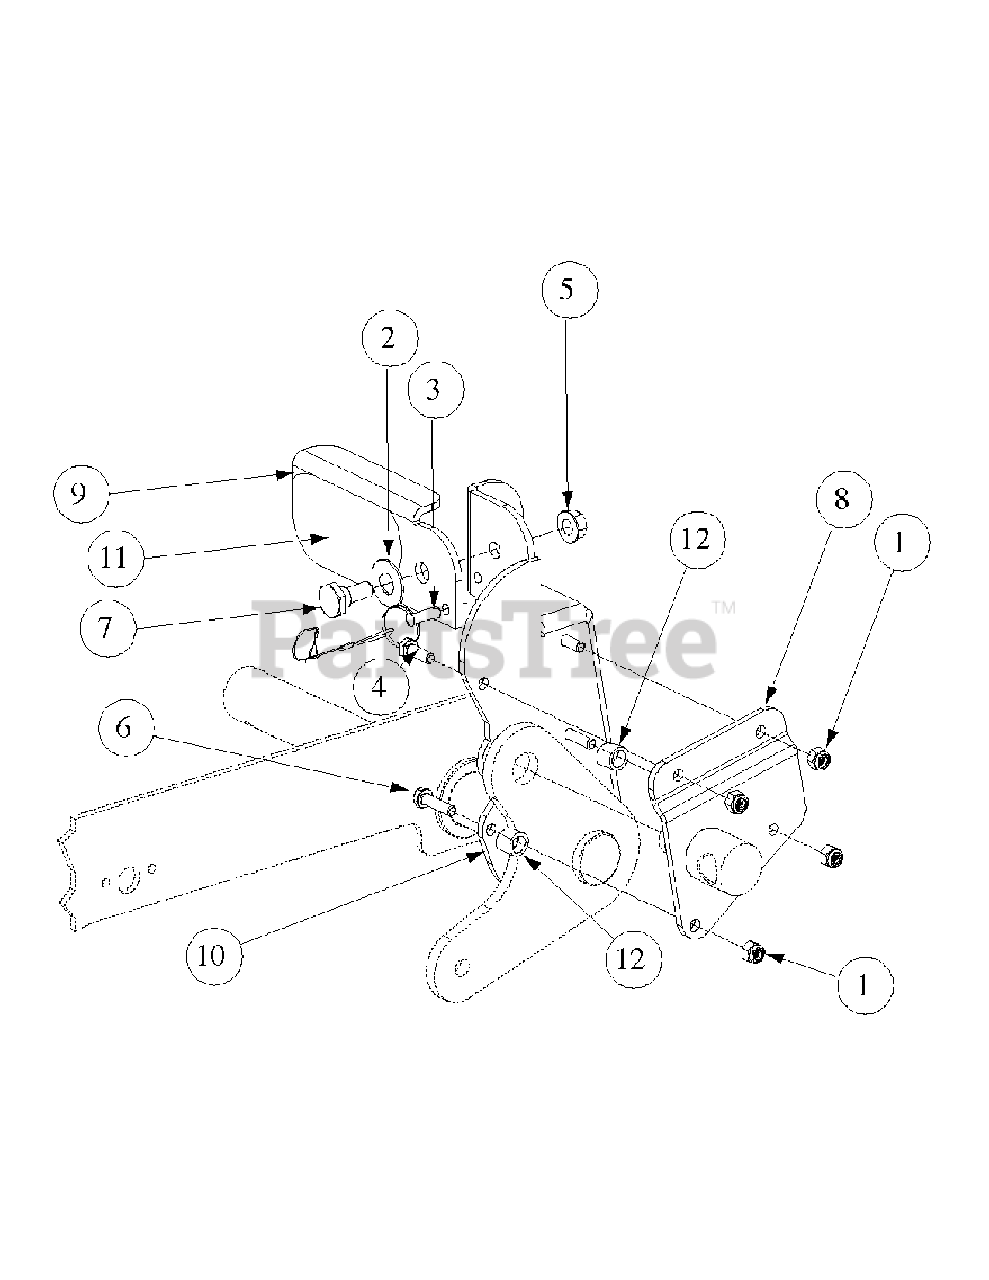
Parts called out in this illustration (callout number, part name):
1	Lock Nut, Nylon Insert, 1/4-20
2	Washer, 1/2 x 1 Shim
3	Detent Pin w/12" Lanyard
4	Hex Cap Screw, 1/4-20, .75
5	Hex Nut, Flange Lock 3/8-16
6	Hex Cap Screw, 1/4-20, 1.00
7	Shoulder Screw, .50 x .27 Lg., 3/8-16
8	Foot Lift Backup Pedal
9	Deck Foot Pedal Lift
10	Deck Foot Pedal Lift
11	Deck Foot Lift Pad
12	Turnbuckle Sleeve
